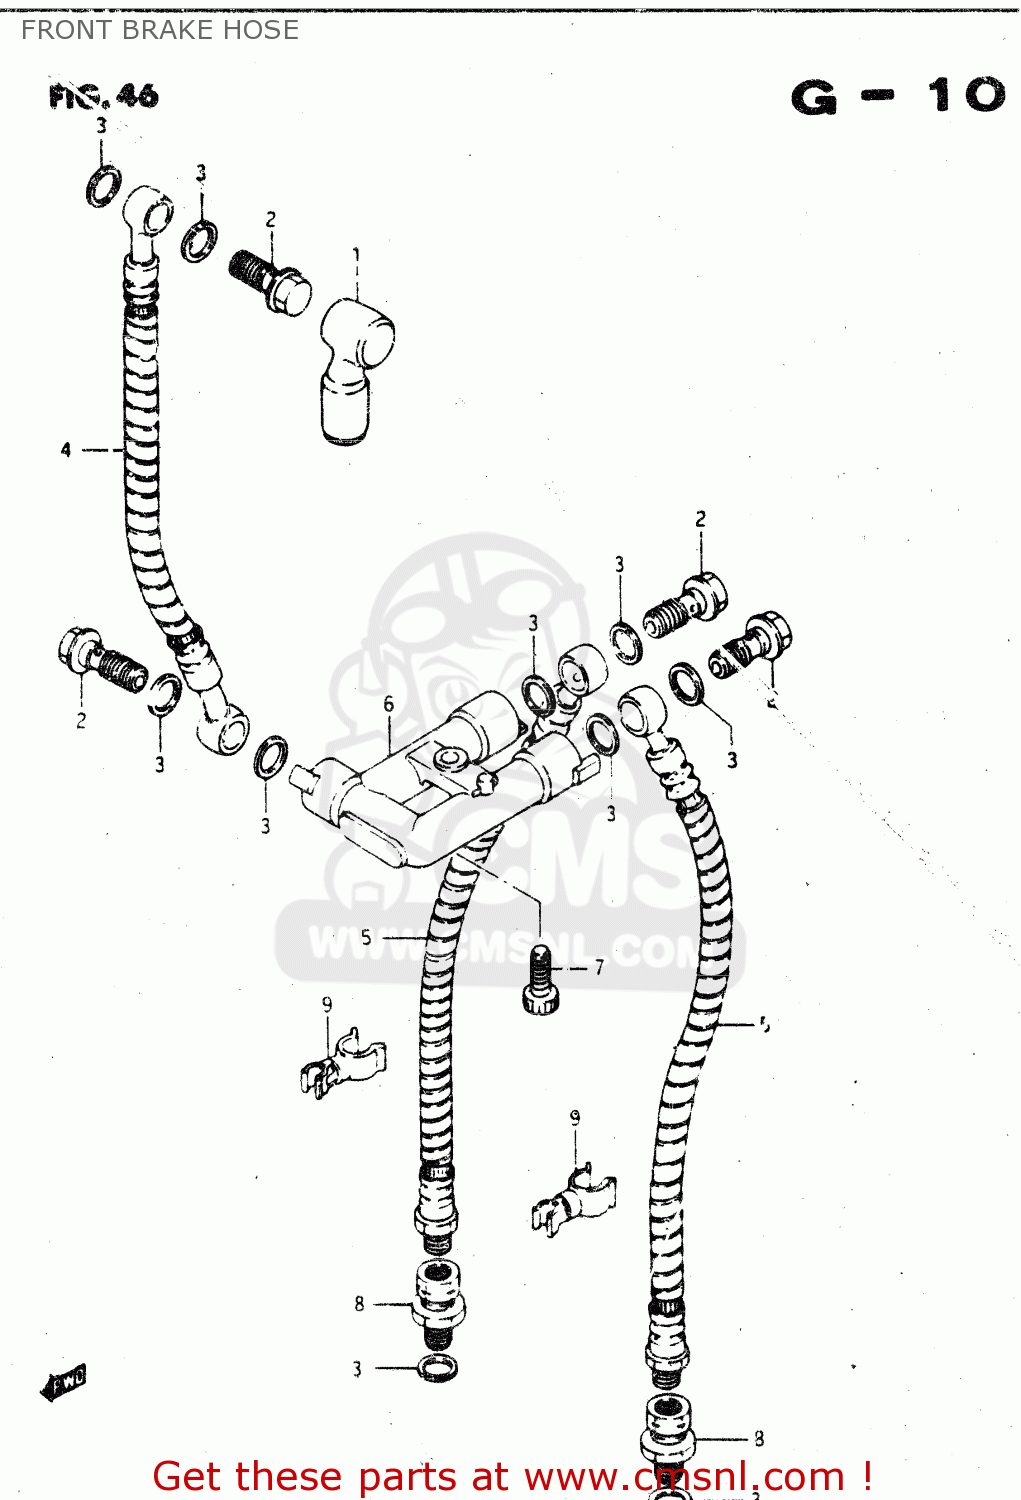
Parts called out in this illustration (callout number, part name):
1	BOOT,MASTER CYLINDER
2	BOLT UNION
3	WASHER(10X15X1.5)
4	HOSE,FRONT BRAKE NO.1
5	HOSE,FR BRAKE NO.2
6	JOINT,BRAKE HOSE
7	BOLT
8	ADAPTER,BRAKE HOSE
9	CLAMP
